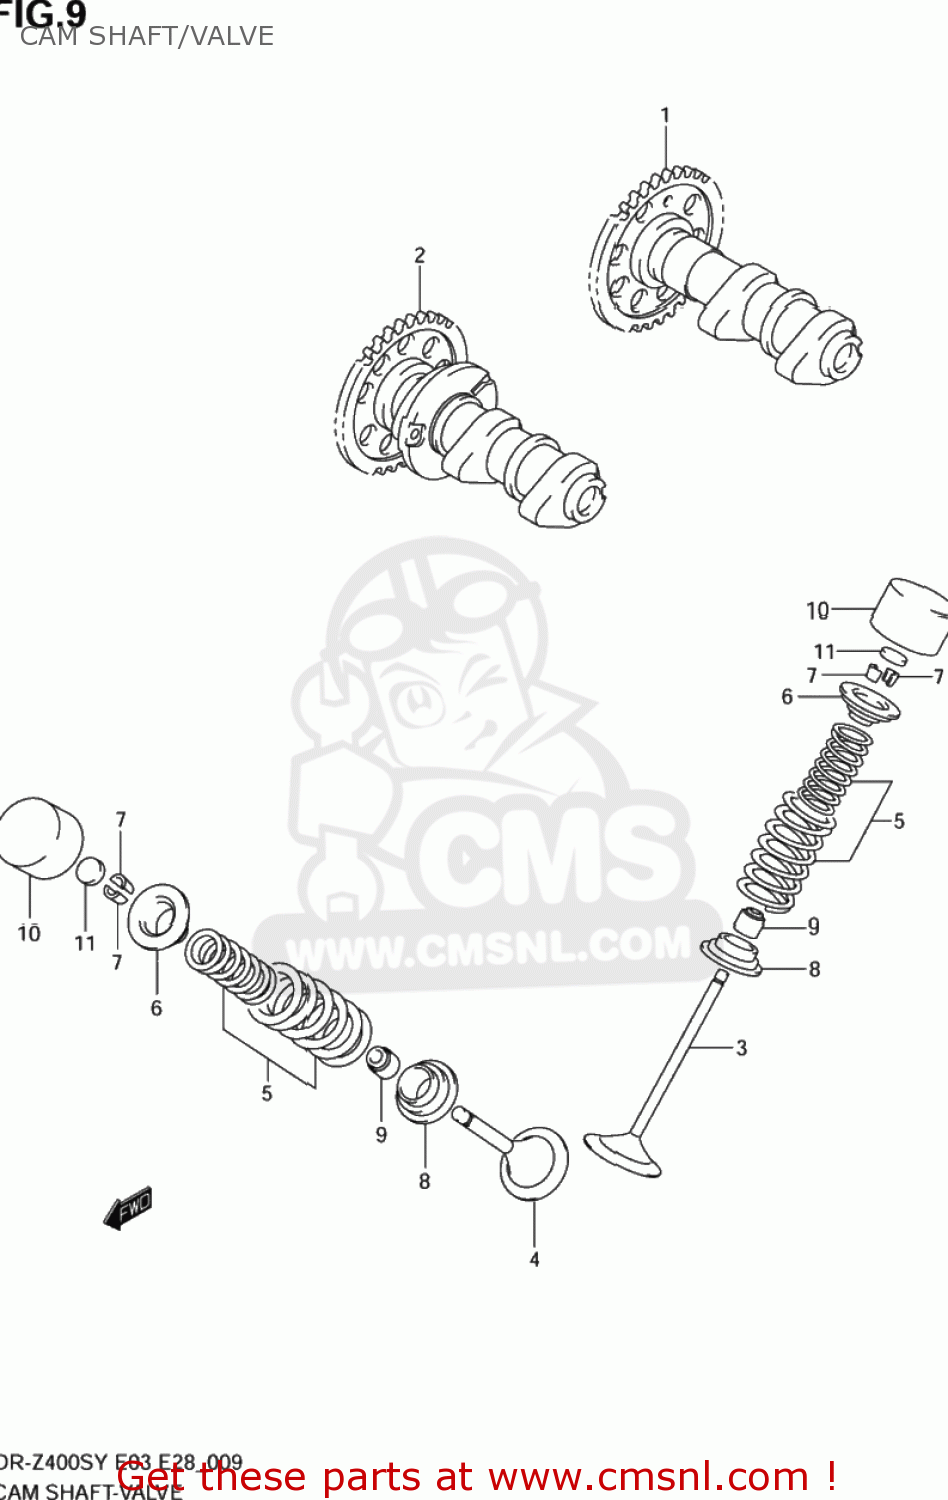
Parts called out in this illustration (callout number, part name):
1	CAMSHAFT,INTAKE
2	CAMSHAFT COMP,EXHAUST
3	VALVE,INTAKE
4	VALVE,EXHAUST
5	SPRING SET,VALVE
6	RETAINER,VALVE SPRING
7	COTTER VALVE
8	SEAT,VALVE SPRING
9	SEAL,OIL(5X10X9.7)
10	TAPPET
11	SHIM,TAPPET(T:2.3)
12	SHIM SET,TAPPET
13	CASE,TAPPET SHIM
